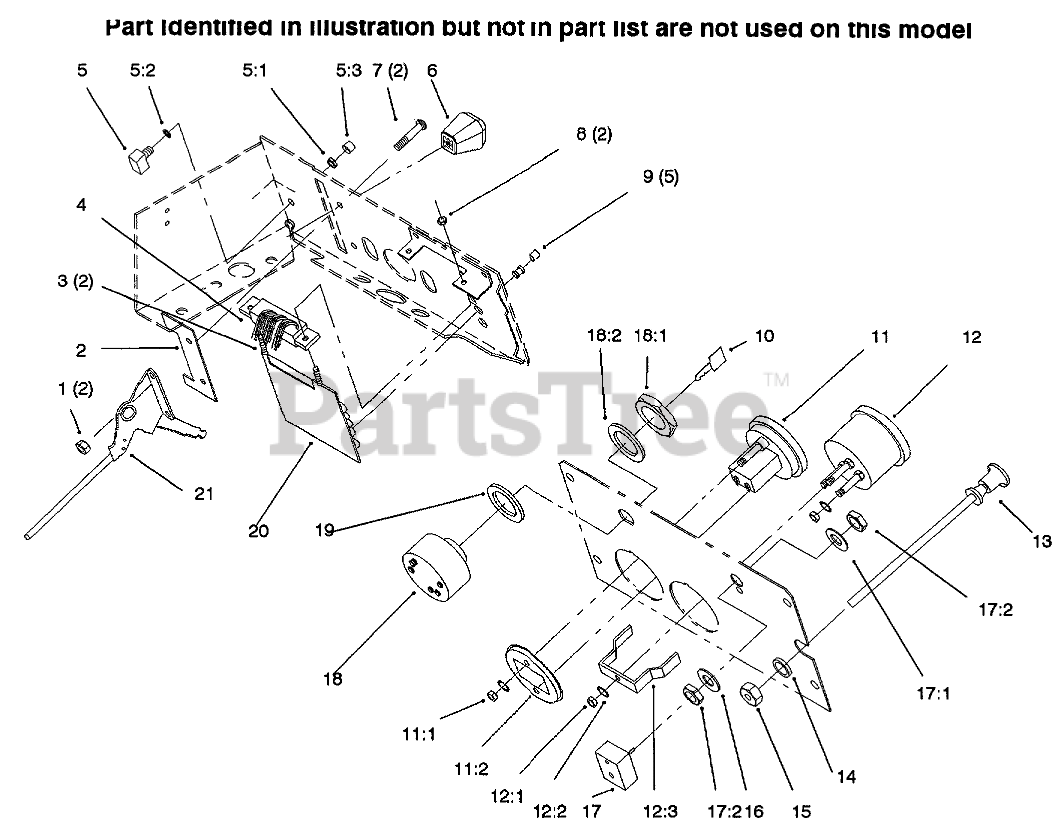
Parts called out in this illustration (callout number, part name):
1	Nut
2	Washer
3	Screw
4	P.C. BOARD HARNESS
5	SWITCH-PUSH BUTTON
7	SCRW-PHC
8	NUT-HEX
9	ASSY LENS & BUSHING
10	KEY-IGNITION
11	Hourmeter
11:1	NUT-HEX, KEPS
11:2	Retainer
12	VOLTMETER
12:1	NUT-HEX
12:2	WASHER-LOCK
12:3	CLAMP-MOUNTING
13	CONTROL-CHOKE
14	WASHER-FLAT
15	NUT-HEX PALNUT
16	WASHER
17	SWITCH-LIGHTS
17:1	TAB-WASHER
18	IGNITION SWITCH ASM
18:2	WASHER-LOCK
19	WASHER
20	Board-Pc
21	CONTROL-THROTTLE
